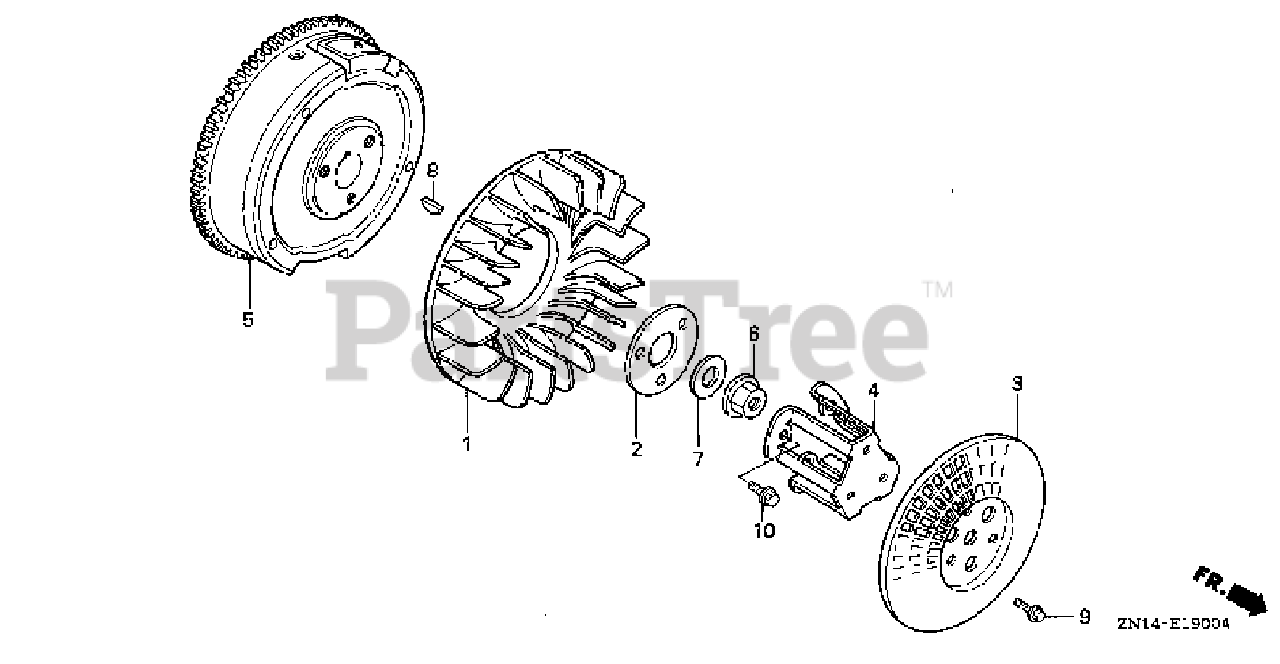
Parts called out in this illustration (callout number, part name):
1	FAN, COOLING
2	PLATE, COOLING FAN SETTING
3	GRID, SCREEN (P.T.O.)
4	HOLDER, SCREEN GRID
5	FLYWHEEL
6	NUT, FLANGE (20MM)
7	WASHER (20MM)
8	KEY, SPECIAL WOODRUFF (25X18)
9	BOLT, FLANGE (6X12)
10	BOLT, FLANGE (8X16)
